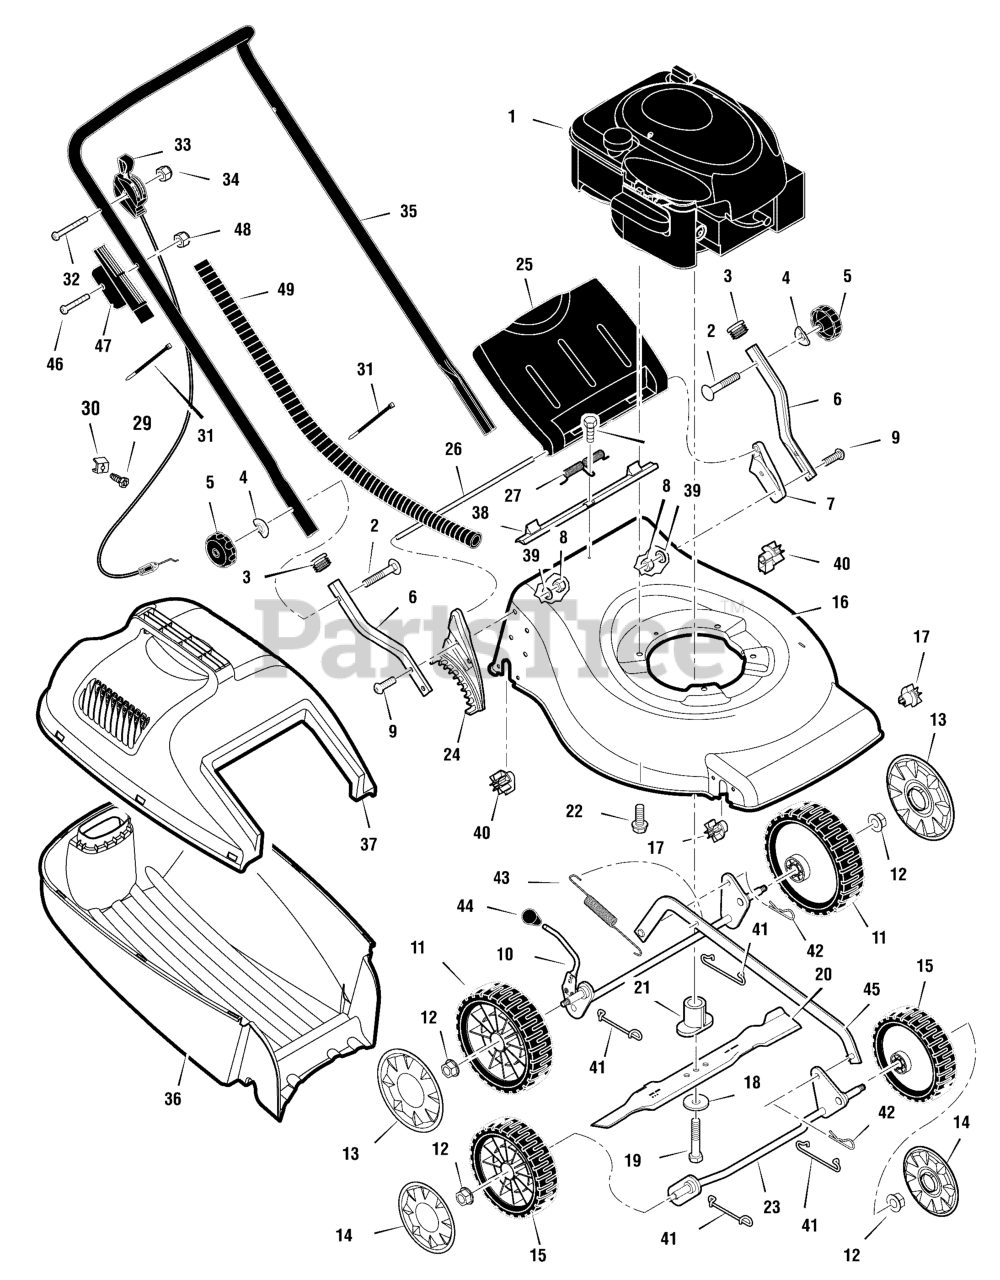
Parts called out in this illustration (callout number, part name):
1	ENGINE, Briggs & Stratton
3	PLUG, 7/8 inch
4	WASHER
6	HANDLE, Lower
7	BRACKET, Left Handle
8	LOCKNUT
9	BOLT, M8x1.25
10	CROSSBAR, Rear Assembly
11	WHEEL, 200 mm
12	LOCKNUT, 3/18-16
13	CAP, Hub, 200 mm
14	CAP, Hub, 175 mm
15	Wheel, 175 mm
16	HOUSING, Mower
17	BUSHING, Front Crossbar
18	WASHER, Belleville
19	BOLT
20	BLADE, 19 inch
21	ADAPTER, Blade
22	BOLT, Engine Mounting
23	CROSSBAR, Front Assembly
24	BRACKET, Right Handle Index
25	DOOR, Rear
26	ROD, Rear Door
27	SPRING, Torsion
30	CLAMP, Cable
31	TIE, Cable
33	CONTROL, Throttle
34	LOCKNUT
35	HANDLE, Upper
36	CATCHER, Grass Bottom, 19"
37	CATCHER, Grass Top, 19"
38	SEAL, Rear Door, 19"
39	WASHER, Lock Split
40	BUSHING, Rear Crossbar
41	CLIP, Crossbar
42	CLIP, Hair Pin
43	SPRING, Extension
44	KNOB, Height Adjuster
45	LINK, Assembly Single Lever, 19"
46	SCREW
47	INTAKE, Remote Air
48	LOCKNUT
49	HOSE, Remote Air Cleaner
